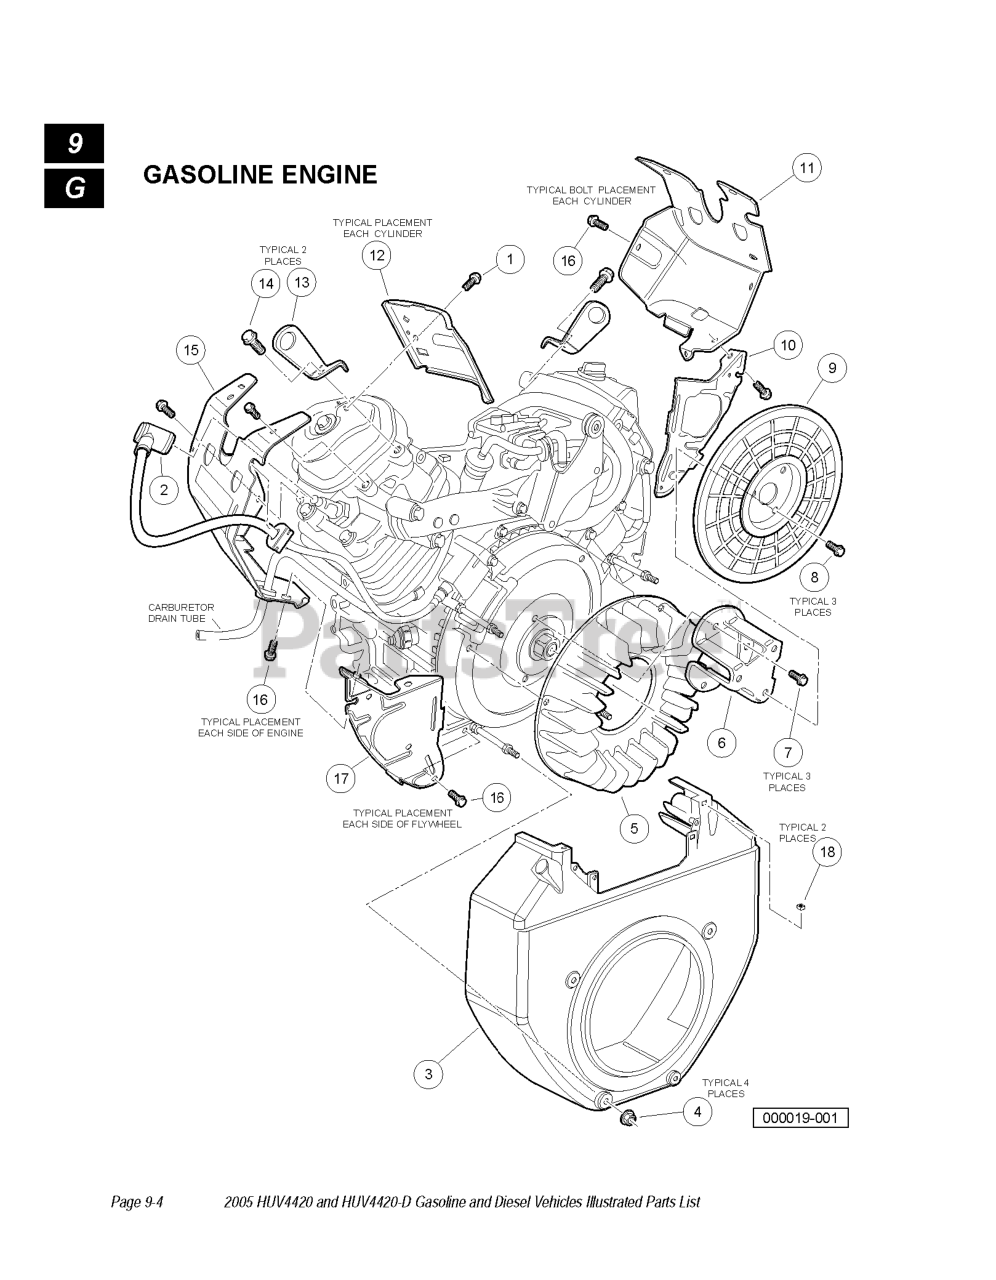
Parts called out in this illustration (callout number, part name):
1	BOLT, FLANGE, M6 X 11 X 4
2	CAP ASSY, NOISE SUPPRESSOR
3	COVER, FAN, BRIGHT RED
4	NUT, FLANGE, M6
5	FAN, COOLING
6	HOLDER, SCREEN GRID
7	BOLT, FLANGE, M8 X 1.25 X 16
8	BOLT, FLANGE, M6 X 1 X 12
9	GRID, SCREEN, P.T.O.
10	PLATE, R SIDE
11	SHROUD, R
12	SHROUD, HEAD
13	HANGER, ENGINE
14	BOLT, FLANGE, M8 X 1.25 X 20
15	SHROUD, L
16	BOLT, FLANGE, M6 X 1 X 12, CT2
17	PLATE, L SIDE
18	NUT, SQUARE, 5MM
